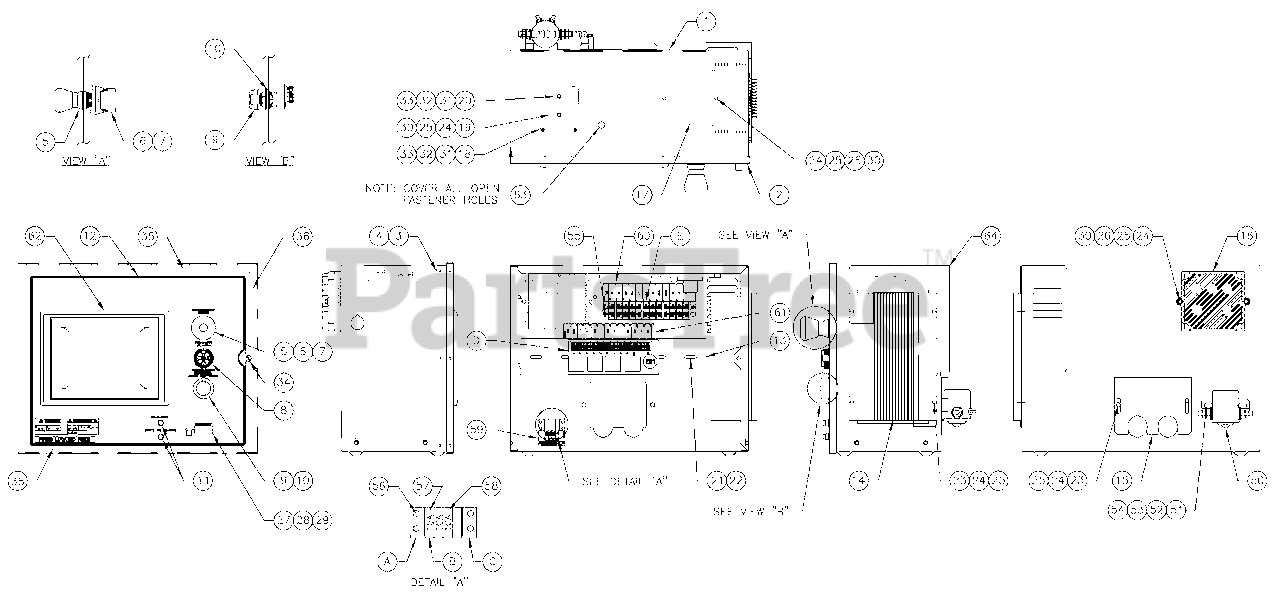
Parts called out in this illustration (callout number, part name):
1	ENCLH/G CONTROL PANEL
2	COVER CONTROL PANEL
3	HINGE CONTINUOUS H PANEL
4	RIVET POP .125X .275SS
5	SWITCH E STOP
6	CONTACT BLOCK NC
7	CONTACT BLOCK NO
8	SOUNALERT BUZZER
9	KEY SWITCH ON-OFF-ON MAINTAIN
10	KEY SWITCH SPACER FOR HOBBS
11	PILOT LIGHT 8MM RED LED
12	DECAL CONTROLG
13	RAIL SNAPTRACK PCB HOLDER BULK
14	ASSY PCB 10A UL BATT CHRGR 12V
15	PLATE HARNESS CLAMP
16	ASSY PCB PWR AVR W/AMP HEADER
17	ASSY PCB BOSCH GOV DRIVER
18	CB 4.5X1 AUT30KW CNT45K
19	DIO BRIDGE25A 600V
20	RES WW 25R 5% 25W QK CONN
21	SCREW PHTT M4-0.7X 10ZYC
22	W ASHER FLAT M4
23	SCREW HHPM M5-0.8 X 12
24	W ASHER FLAT M5
25	W ASHER LOCK M5
26	SCREW PPHM M5-0.8X 30SS
27	CONN DUST CAP W/CHAIN DB9
28	SCREW PHTT M3.5-0.6 X 10
29	WASHER FLAT M3.5
30	NUT HEX M5-0.8 G8 CLEAR ZINC
31	WASHER LOCK M3
32	WASHER FLAT M3
33	NUT HEX M3-0.5 G8YELCHR
34	M5-0.8 CAPTIVE PANEL KNLD HD
35	SEALCOVER 3.18X12.7X382
36	SEALCOVER 3.18X12.7X283
37	HARNESS G-PANELCPLSW
50	RELAY SOLENOID 12VDC PNL MNT
51	SCREW HHC 1/4-20X 3/4G5
52	WASHER FLAT 1/4-M6 ZINC
53	WASHER LOCK M6-1/4
54	NUT HEX 1/4-20 STEEL
55	SCREW PHTT +6-32X 5/8ZYC
56	SCREW PHTT +6-32X 3/8ZYC
57	FUSE ATO TYPE 15 AMP (BLUE)
58	FUSE ATO TYPE 10 AMP (RED)
59	DECAL CPL CONTROL PANEL FUSES
60	DECAL 24VDC TB3
61	DECAL H-100 RELAY BRD 24V RB2
62	TOUCH PANEL CONFIG GEN MQT
63	SEAL WEATHER .45"DIA
64	COVER CONTROL PANEL SIDE
A	ADPTR RH SIDE WICKMANN 178.6191
B	HOLDERFUSE WICKMANN 178.6150
C	ADPTR LH SIDEWICKMANN 178.6192
D	ASSY PCB G-PANEL RELAY 12VDC
E	BLOCK TERM 20A 12X 6X 1100V
